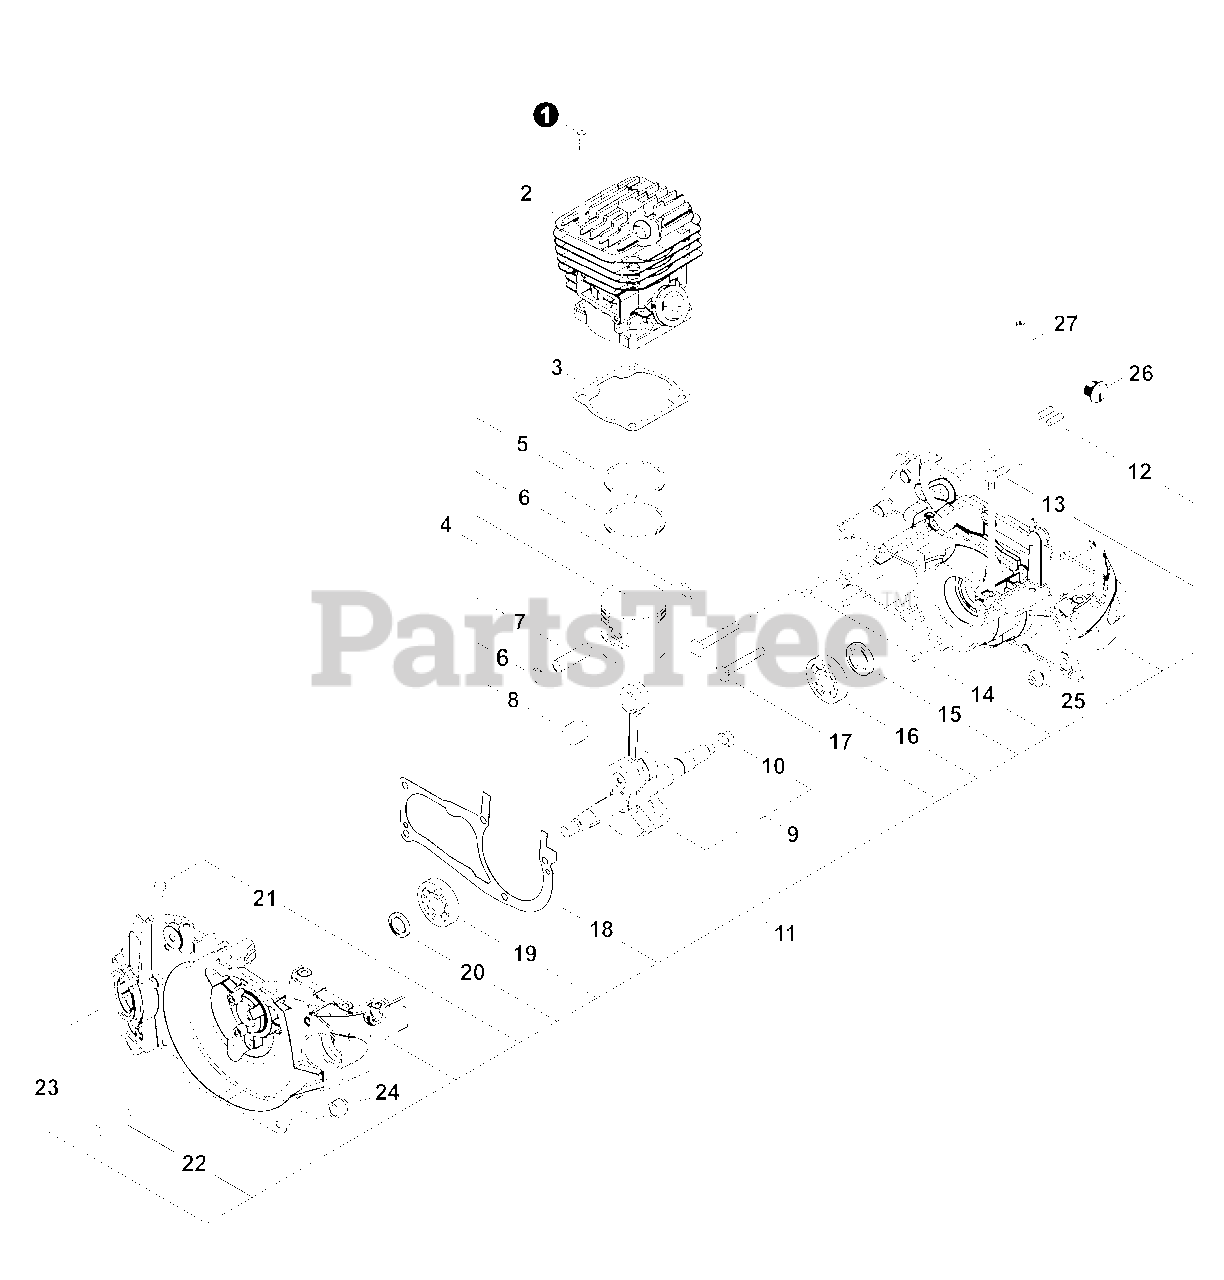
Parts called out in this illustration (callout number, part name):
1	BOLT M5×18
2	CYLINDER
3	GASKET, CYLINDER
4	PISTON KIT
5	RING, PISTON
6	RING, SNAP
7	PIN, PISTON 11
8	BEARING, NEEDLE 11
9	CRANKSHAFT ASSY
11	CRANKCASE ASSY
12	PIN, LOCATING Ø4×11
13	CONNECTOR, PIPE
14	PIN, LOCATING 4×8
15	SEAL, OIL 15
16	BEARING, BALL 6202 C3
17	BOLT, STUD 8
18	GASKET, CRANKCASE
19	BEARING, BALL 6201 C3
20	SEAL, OIL 12
21	VENT ASSY
22	BOLT M5×35
23	BOLT M5×18
24	CUSHION M
25	CUSHION
27	PIPE, FUEL 3×6×110
